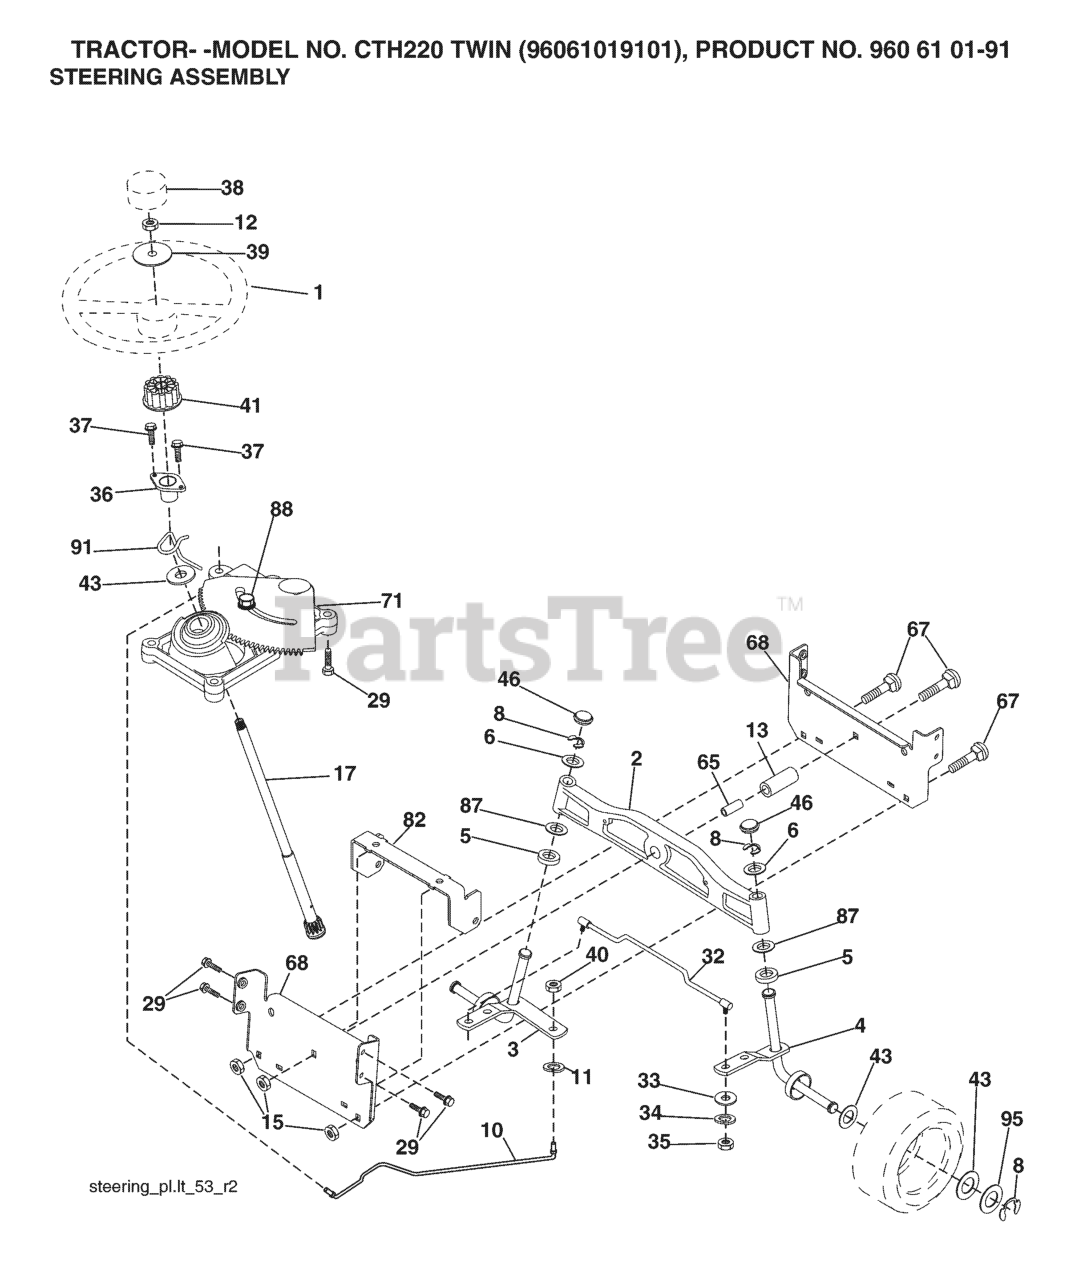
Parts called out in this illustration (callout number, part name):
1	STEERING WHEEL
2	AXLE ASSY FRONT
3	SPINDLE.ASM.LH.15"TIRES
4	SPINDLE.ASM.RH.15"TIRES
5	THRUST WASHER
10	DRAGLINK.15".TIRES.2001
11	WASHER, LOCK 3/8
12	NUT.HEX.1/2-20
13	TUBE, PIVOT AXLE
15	NUT
17	SHAFT ASM STRG
29	SCREW, 3/8-16X3/4
32	TIE ROD
33	WASHER M
34	WASHER.LOCK.HVY.HLCL.SPR.5/16
35	NUT, CROWNLOCK
36	BUSHING, STRG. BLK
37	SCREW.TT.#10-32X.5.3/8.FLANGE
38	INSERT.CAP.STRG.WH.GRAY
39	WASHER 9/16"ID, 2 3/8"OD
40	NUT CROWNLOCK 3/8-24
41	ADAPTER, WHEEL STNG..
46	CAP.SPINDLE.BLACK
65	SPACER BRACE AXLE
67	BOLT CARRIAGE
68	BRACE.AXLE.15"TIRES
71	STEERING ASM
82	BRACKET.SUSP.CHASSIS.FRONT.15
87	WASHER, FLAT .781 X 1 1/2"
88	BOLT, SHOULDER 7/16-20
91	CLIP.STEERING
95	WASHER.HARDENED
